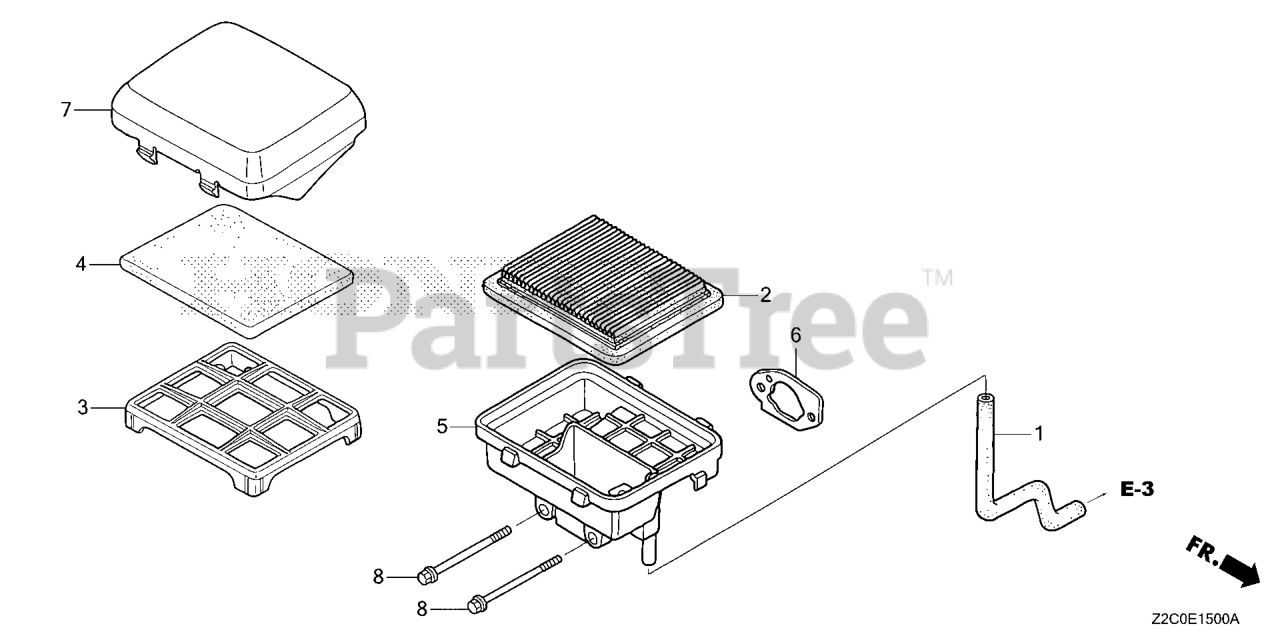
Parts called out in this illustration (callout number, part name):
1	TUBE, BREATHER
2	ELEMENT, AIR CLEANER (TOYO ROKI) (ENGINE NO.)
3	GRID, AIR CLEANER
4	FILTER (OUTER) (WET)
5	HOUSING, AIR CLEANER
6	GASKET, AIR CLEANER
7	COVER, AIR CLEANER
7	COVER, AIR CLEANER (DUAL)
8	BOLT, FLANGE (6X112) (CT200)
